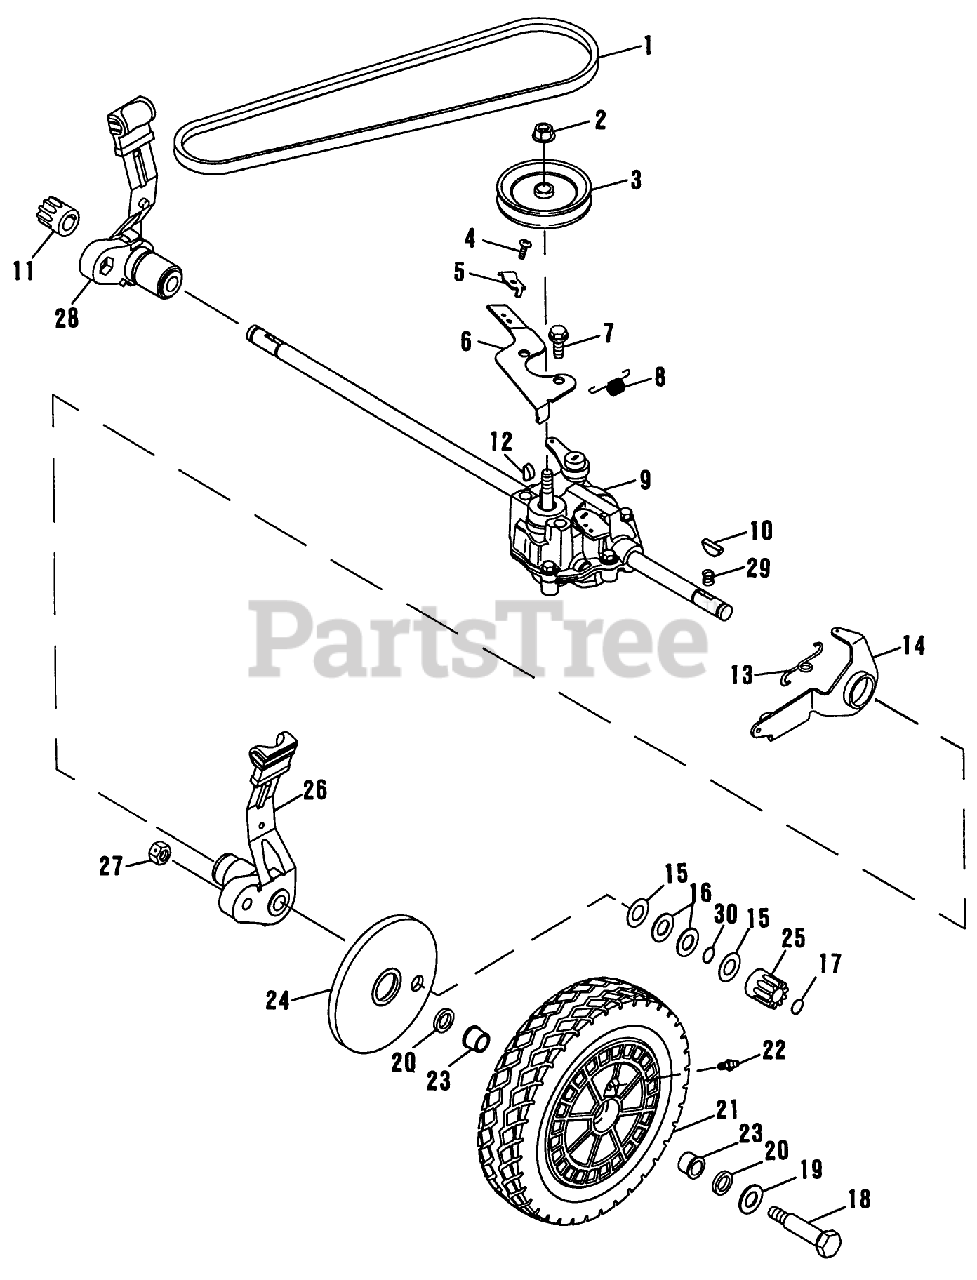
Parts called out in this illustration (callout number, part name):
1	V BELT SM
3	PULLEY TRANS ADAMS
5	CLAMP-CABLE
8	SPRING-EXTENSION
9	TRANSMISSION ASSEM
10	KEY
11	PINION(R)MET ALLEG
12	KEY GALGER
13	LINK
15	THRUST WASHER
16	WASHER-THRUST
17	RETAINING RING
19	SPACER
20	WASHER
22	FITTING LINCOLN
23	BEARING
25	PINION(L)MET ALLEG
27	NUT-JAM, LOCKING
29	SPRING
30	RET RING
